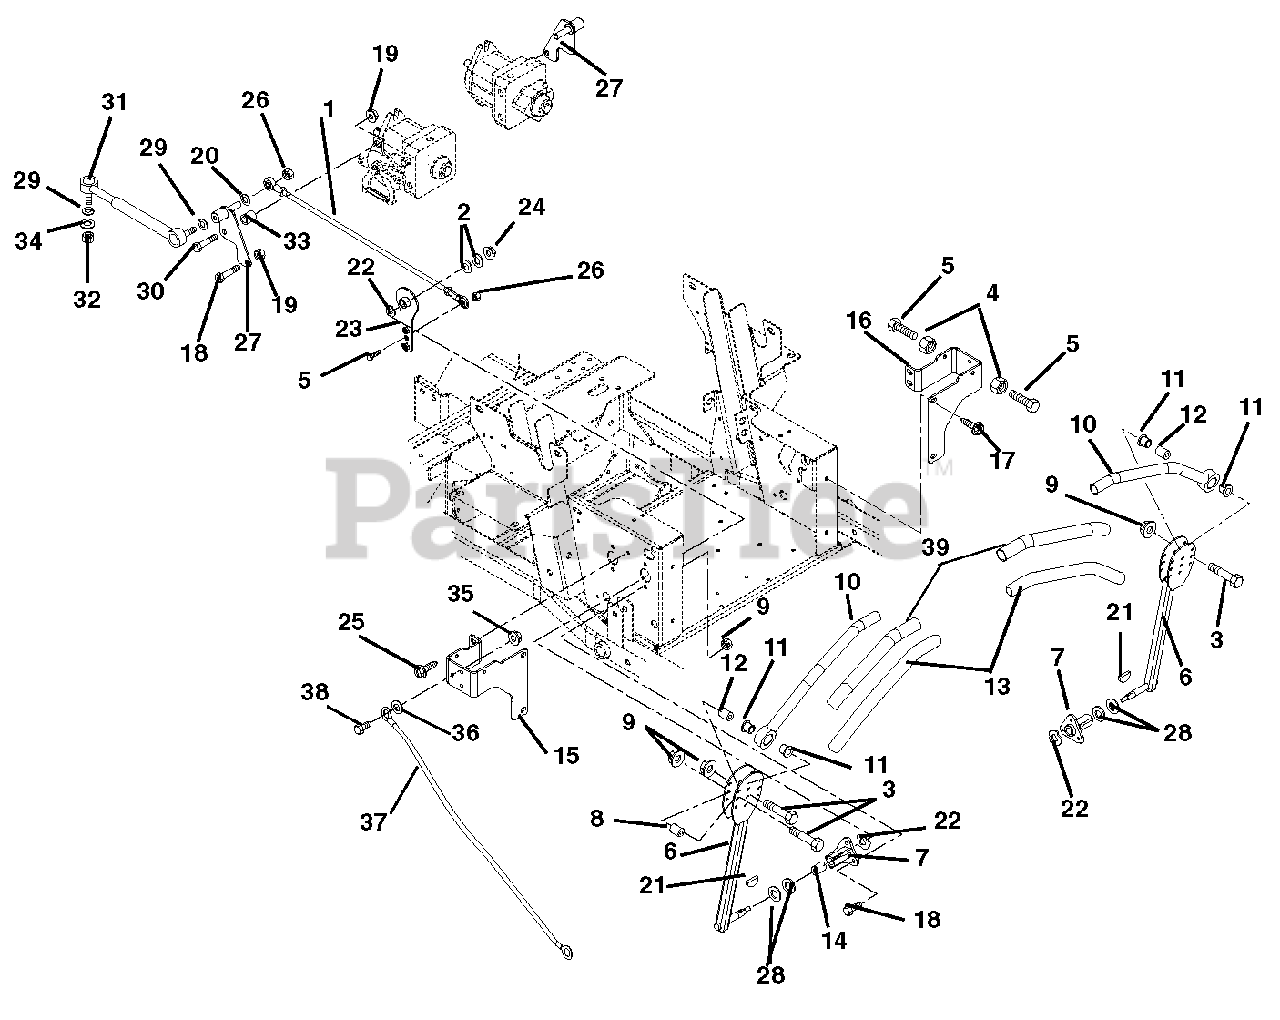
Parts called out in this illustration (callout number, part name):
1	Assembly, Steering Rod .38 Rod x 21.65
2	Washer, Flat Steel .408 x .812 x .065
3	Bolt, Hex .31-18 x 1.75 Grade 5
4	Nut, Hex Jam .375-16
5	Bolt, Hex .375-16 x 1.75
6	Weldment, Control Arm
7	Bushing, Flange
8	Bushing, Eccentric .31 x .75 x .97
9	Nut, Locking Top Flange .31-18
10	Handle Weldment, Left Hand
11	Bushing, Flange Nylon .762 x 1.48 x .44
13	Grip, Handlebar
14	Bushing .625 x .75 x .50
15	Bracket, Stop Right Hand
16	Bracket, Stop Left Hand
17	Screw, Tapping .38-16 x .75 Hex Washer Head
18	Bolt, Hex .31-18 x .75 Grade 5
19	Nut, Locking Top Flange .31-18
20	Washer, Locking .38 x .094 Regular
21	Key, Woodruff .13 x .63
22	Washer, Wave
23	Weldment, Pivot Arm
24	Nut, Locking Top Flange .38-16
25	Screw, Tapping .38-16 x .50 Hex Washer Head
26	Nut, Locking Jam Center .375-16
27	Weldment, Return to Neutral/Damper/Rod End
28	Washer, Flat Steel .63 x 1.005 x .062
29	Washer, Locking .31 x .078
30	Bolt, Hex .31-18 x 1.25 Grade 5
31	Damper, Control
32	Nut, Locking Nylon M8-1.25
33	Spacer .318 x .43 x .375
34	Washer, Flat Steel .38 x .875 x .083
35	Nut, Locking Top Flange .25-20
36	Washer, Flat Steel .265 x .50 x .087
37	Cable, Seat Prop
38	Bolt, Hex .25-20 x .75 Grade 5
39	Tube, .88ID x 1.00OD x 10.7
